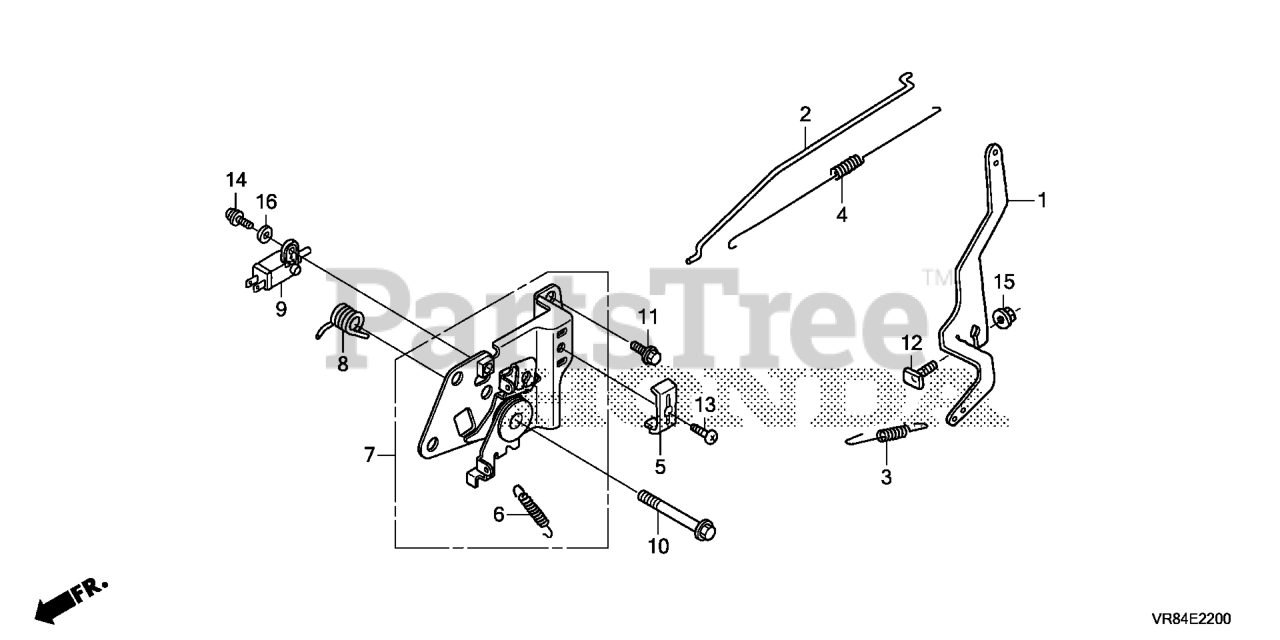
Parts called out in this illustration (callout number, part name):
1	ARM, GOVERNOR
2	ROD, GOVERNOR
3	SPRING, GOVERNOR
4	SPRING, THROTTLE RETURN
5	HOLDER, CABLE
6	SPRING, LEVER
7	BASE, CONTROL
8	SPRING, CONTROL LEVER RETURN
9	SWITCH ASSY., ENGINE STOP
10	BOLT, FLANGE (6X50)
11	BOLT, FLANGE (6X14)
12	BOLT, GOVERNOR ARM
13	SCREW, PAN (5X16)
14	SCREW-WASHER (4X12)
15	NUT, FLANGE (6MM)
16	WASHER, PLAIN (4MM)
